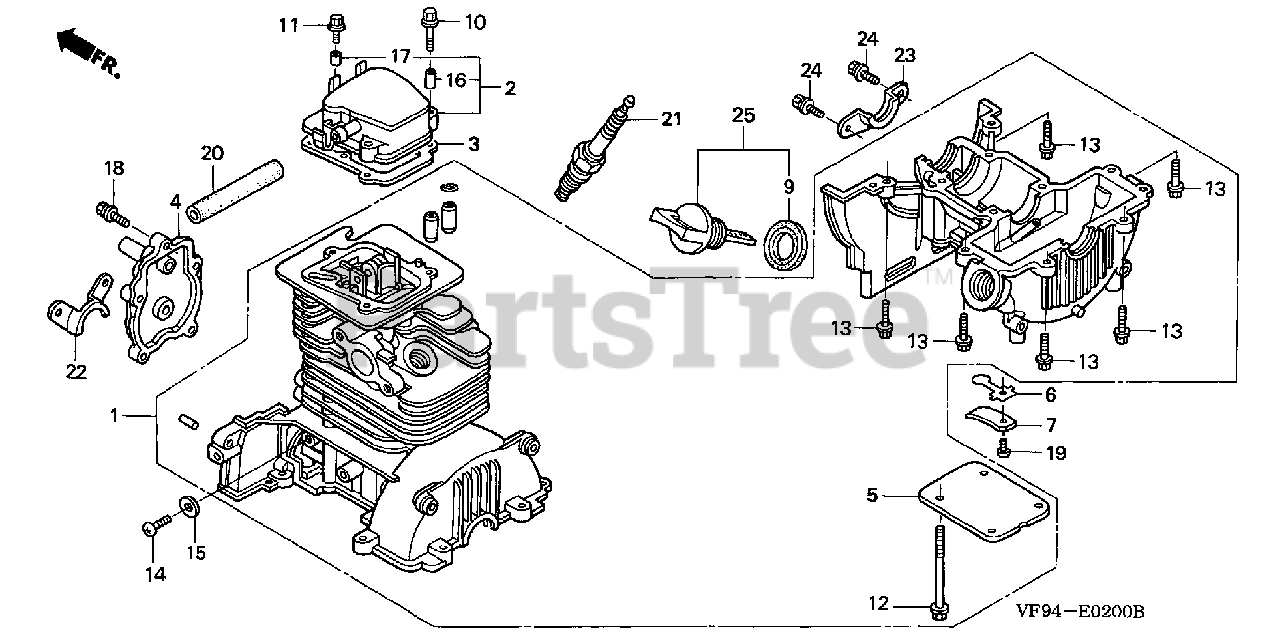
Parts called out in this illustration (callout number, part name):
1	CRANKCASE SET
2	COVER, HEAD
3	GASKET, HEAD COVER
4	COVER, CAMSHAFT
5	COVER, OIL OUTLET VALVE
6	VALVE, OIL OUTLET
7	PLATE, STOPPER
9	GASKET, OIL FILLER CAP
10	BOLT, FLANGE (5X22)
11	BOLT, FLANGE (5X14)
12	BOLT, FLANGE (5X55)
13	BOLT, FLANGE (5X18)
14	SCREW, PAN (6X8)
15	WASHER, SEALING (6.5MM)
16	COLLAR, HEAD COVER
17	COLLAR A, HEAD COVER
18	BOLT-WASHER (4X16)
19	SCREW, PAN (3X5)
20	BULK HOSE, VACUUM (7X3000) (7X68)
21	SPARK PLUG (U16FSR-UB) (DENSO)
21	SPARK PLUG (CR5HSB)
22	GUARD A, GRASS
23	GUARD B, GRASS
24	BOLT-WASHER (4X10)
25	CAP ASSY., OIL FILLER
